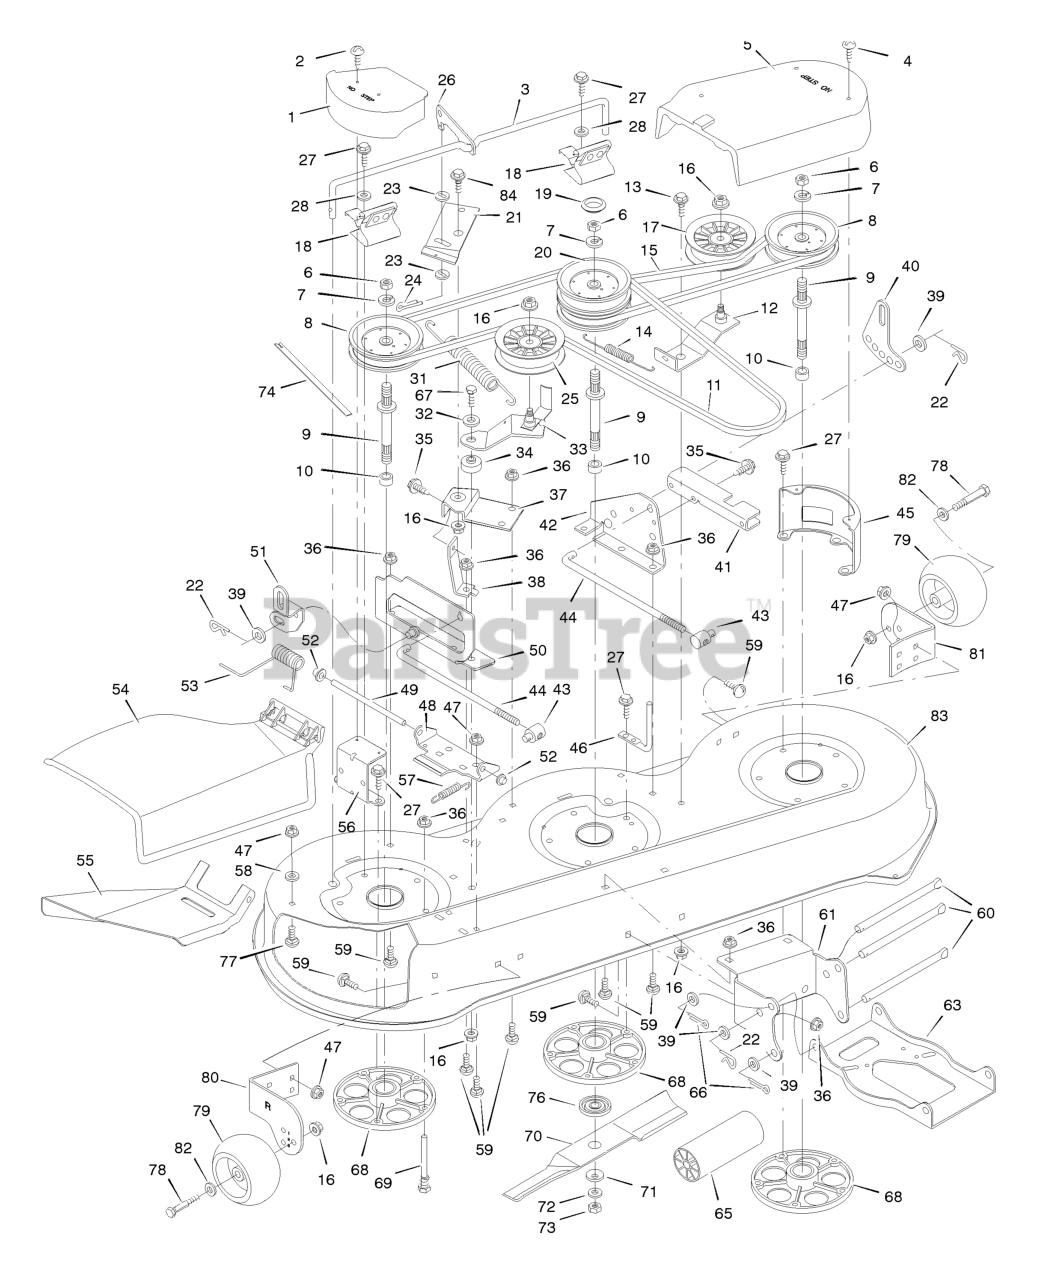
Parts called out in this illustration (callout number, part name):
1	Cover, Pulley
3	Rod, Brake
5	Cover, Left Pulley
6	Nut, Hex
7	Lockwasher
9	Jackshaft
10	Spacer, Bearing
11	Belt, Primary Mower Drive
12	Bracket, Idler
13	Bolt, Shoulder
14	Spring, Extension
15	Belt, Secondary Mower Drive
16	Locknut
17	Pulley, Idler
18	Spring Assembly, Brake
20	Pulley, Stack
21	Bracket, Pivot
22	Pin, Hair
24	Pin, Cotter
25	Pulley, Idler
26	Link, Brake
27	Screw
31	Spring, Extension
33	Bracket, Idler
34	Bushing
36	Nut, Hex
37	Support, Pivot
38	Strut, Pivot
40	Plate, Adjuster
41	Channel, Left Cover
42	Bracket Assembly, Lifter
43	NUT, Adjusting, 1/2-13
44	Rod, Adjuster
45	Bracket, Left Cover
46	Guide, Belt
47	Locknut
48	Bracket, Hinge
49	Rod, Deflector
50	Bracket Assembly, Lifter
51	Link, Suspension
52	Push- On Cap
53	Spring, Torsion
54	Deflector
55	Deflector, Inside
56	Bracket, Cover
57	Spring, Extension
58	Washer
59	Bolt, Carriage
60	Rod, Hanger
61	Bracket, Front Hanger
63	Hanger, Front
66	Pin, Cotter
67	Bolt, Hex
68	Housing, Mandrel
69	Guide, Belt
70	Blade
71	Washer, Belleville
73	Nut, Hex
74	Indicator, Plastic
76	Adapter, Blade
77	Bolt, Carriage
78	BOLT, Gauge Wheel
79	Wheel, Gauge
80	Bracket, Right Gauge Wheel
81	Bracket, Left Gauge Wheel
82	Washer
83	Housing, Mower
84	Bolt, Shoulder
